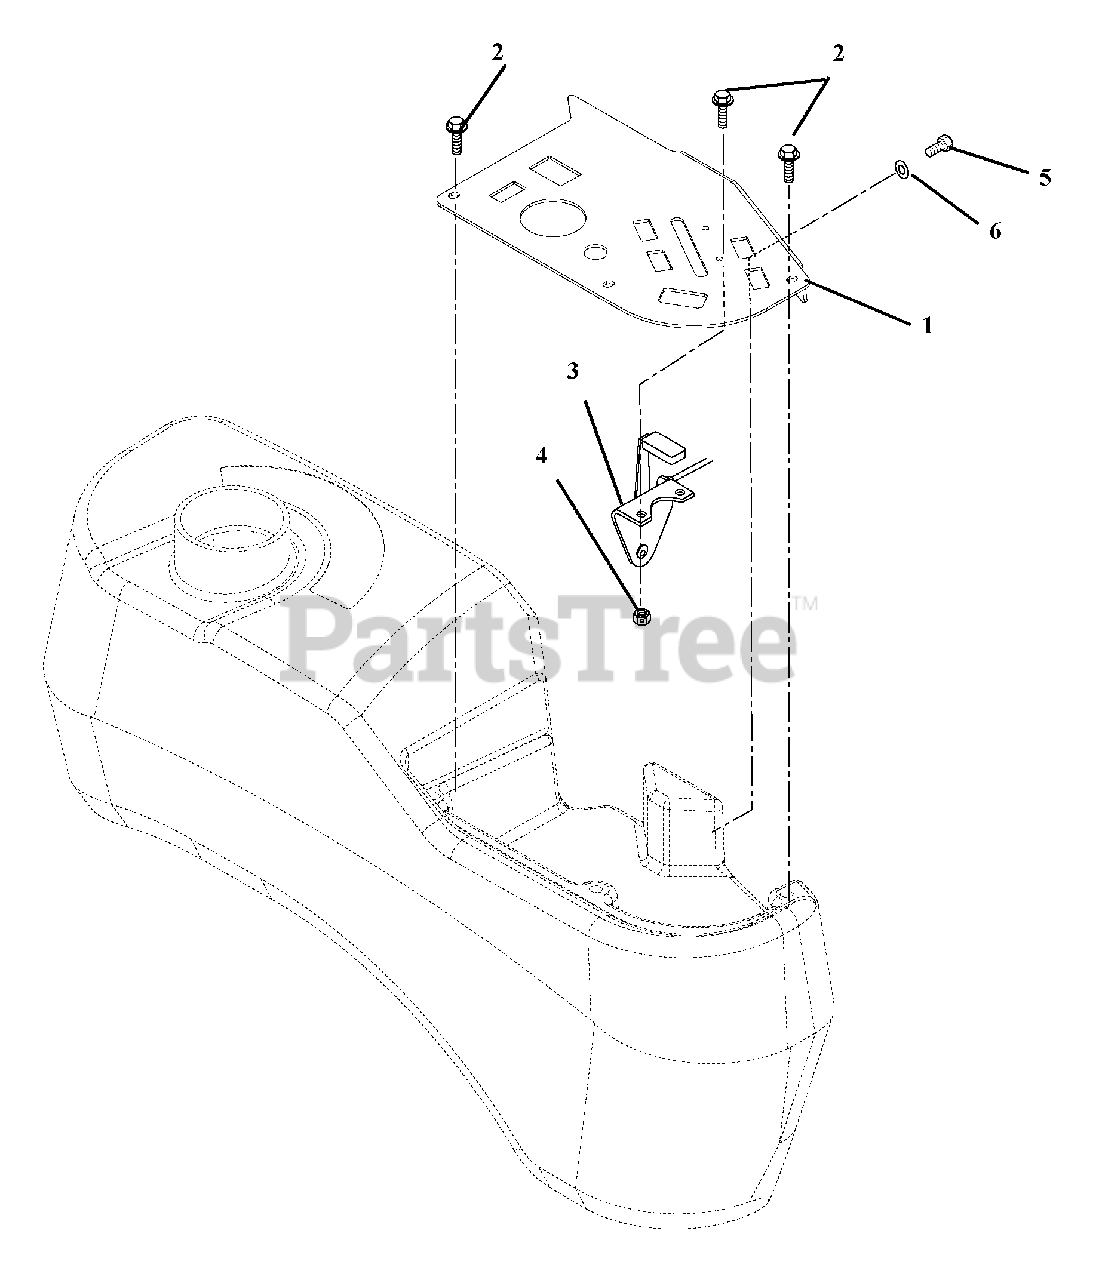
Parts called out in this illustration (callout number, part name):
1	Panel-Control
2	Screw-Machine 10-24 x .50 Hex Washer Head
3	Throttle, Control
4	Nut-Locking-Nylon 10-24 With Insert
5	Bolt-Hex .31-18 x .75 Grade 5
6	Washer-Flat-Steel .38 x .875 x .083
